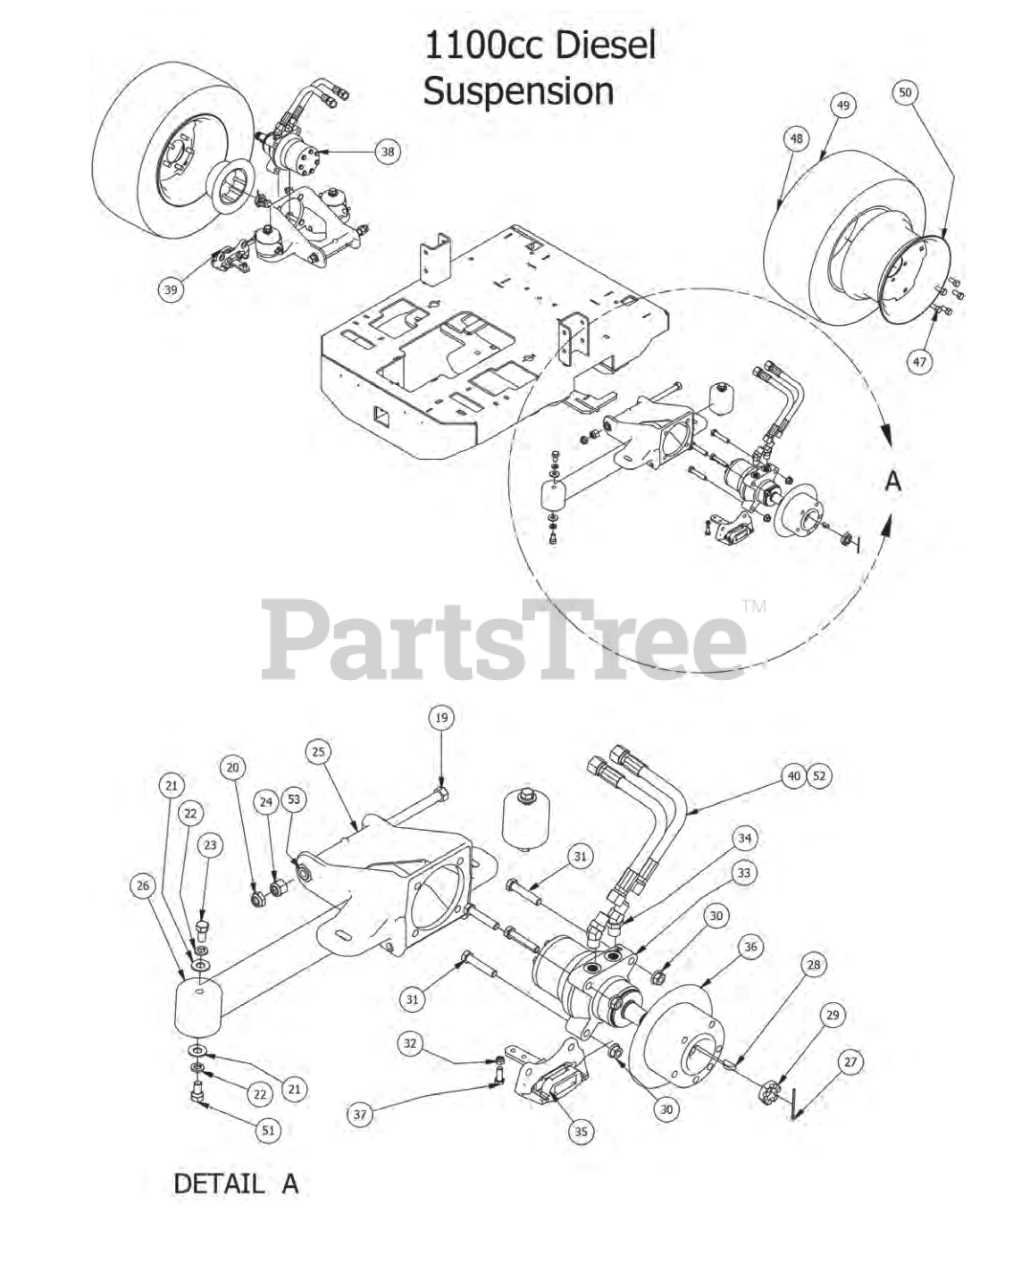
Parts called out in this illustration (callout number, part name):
1	Diesel Back Pump Cover 2008 Bottom
2	Back Cover Hinge Bracket
3	Diesel Back Pump Cover 2008 Top
4	Diesel Hood 3 Cyl
5	5/16" x 1" Carriage Bolt
6	360 ID Plastic Washer
7	1/4" x 5/8" BS C/S 18-8 SS
8	5/16-18x3/4 carriage bolt
9	5/16" Flange Nut
10	1/4 Nylock Nut
11	5/8 Round Insert
12	5/16" x 1" Bolt
13	5/16-18 Nylock Insert Locknut
14	5/16" Knob
15	5/16" x 1 1/4" Carriage Bolt
16	1/4" x 1 1/2" Self Tapping Screw
17	1/4" Flat Washer
18	8" Rubber Bumper
19	5/8"x10" Hex Bolt (Grade8)
20	5/8" Nylock (1/2 Jam)
21	1/2" Washer (Grade 8)
22	1/2" Lock Washer
23	1/2" x 1" Hex Bolt
24	5/8 Std NC Nylock Nut
25	60 Suspension kit Wheel Motor
26	Vibration Mount-Green Dot
27	1/8x2-1/4 cotter pin Zinc
28	Woodruff Key
29	1" Castle Nut for Wheel Motor
30	1/2" Flange Nut
31	1/2" x 2 1/2" Hex Bolt
32	5/16-18 Nylock Insert Locknut
33	18cc Parker Wheel Motor- Right
34	45 Degree Wheel Motor Fitting -6802-10-10
35	XP/AOS Right Brake Caliper
36	Brake Disk
37	3/8" x 1" Hex Bolt
38	18cc Parker Wheel Motor- Left
39	XP/AOS Left Brake Caliper
40	26" Hose Assembly with Adaptors
41	5/8" x 2 1/2" Gr5 Hex Bolt (Coarse)
42	5/8 Std NC Nylock Nut
43	5 V Idler Pulley-BCVI-81
44	5/8" x 1/" Collar W/One Set Screw
45	Steel Pump Cover Latch
46	10-24 X 5/8 BS C/S 18-8 SS
47	1/2-20 x 1-1/2 Lug Bolts Zinc
48	26 x 12.00-12 Tire and Orange Wheel Assembly
49	26 x 12.00 12 Tire
50	12 x 10.5 Wheel AOS Rear
51	1/2-13 1-1/4 Hex bolt
52	26" Hose Only
53	Brass Bushing
54	10-24 Nylock Locknut
